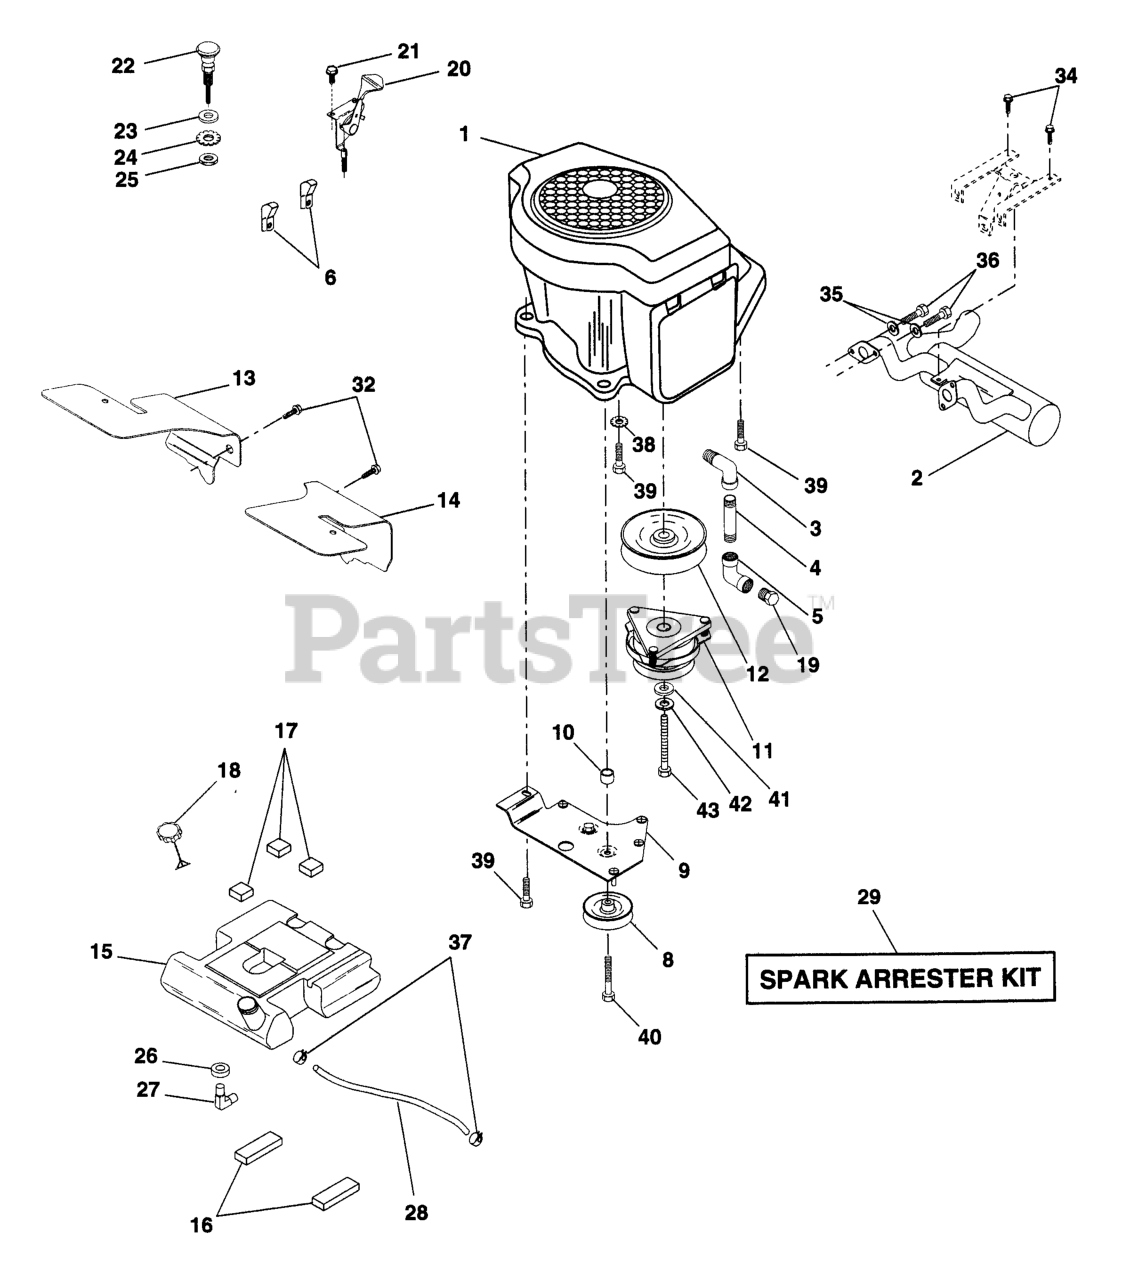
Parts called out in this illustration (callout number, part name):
2	Muffler Asm Kohler VGT
3	STREET ELBOW LT NLA
4	Nipple Pipe 3/8NPT X 3 - 1/2
5	ELBOW
8	RP.IDLER GROOVED
9	STOP KEEPER
11	CLUTCH.ELECT.CVX.105 FT/LB.
12	PULLEY, ENGINE
13	AIR BAFFLE
14	AIR BAFFLE RH
15	FUEL TANK
16	PAD IDLER TI
17	PAD-SPACER LT
18	FUEL CAP
19	PLUG T
20	THROTTLE CONTROL
21	SCREW LT
22	CONTROL.CHOKE.51.00.BLK.W/BEND
23	WASHER
24	LOCKWASHER
25	NUT
26	BUSHING OUTLET T
27	STEM FUEL TANK
28	HOSE
29	SPARK ARRESTOR
32	Screw Thdrol 5/16 - 18 X 1/2
34	SCREW
35	WASHER.LOCK.HVY.HLCL.SPR.5/16
36	Screw Hex 5/16 - 16 UNC X 3/4
37	HOSE CLAMP
38	LOCKWASHER
39	SCREW LT
40	Screw Thdrol 3/8 - 16 X 3 - 1/4
42	LOCKWASHER
43	BOLT
